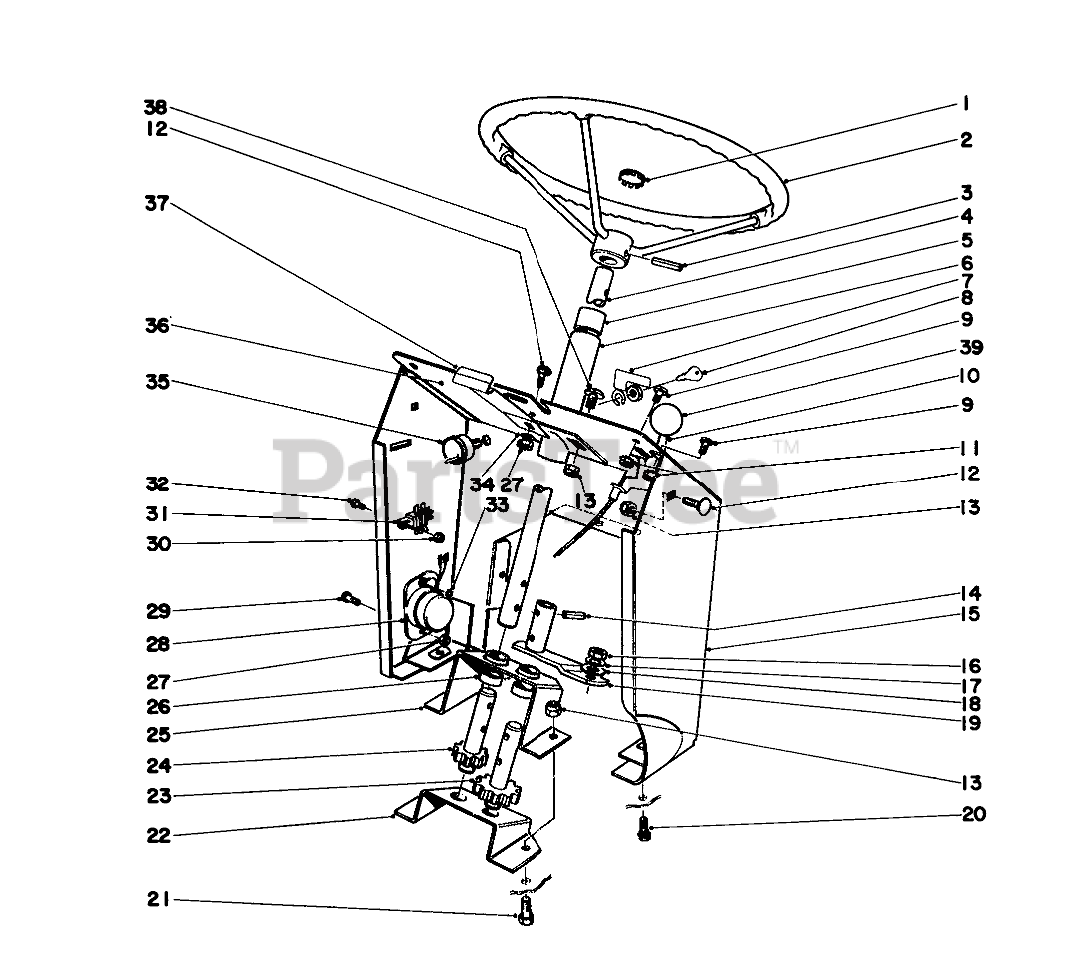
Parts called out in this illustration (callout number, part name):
2	Steering Wheel
3	PIN-ROLL
4	Shaft Steering
5	BUSHING
6	Steering Tube (Incl . Ref. #5)
7	Decal (Model 57003)
9	SCREW-PPH
10	Throttle Control
11	NUT-KEPS
12	SCREW-CARRIAGE
13	NUT-LOCK, CONE
14	PIN-ROLL, SLOTTED
15	Rear Hood Support (Model 57003)
16	NUT-HEX
17	WASHER-LOCK
18	WASHER-FLAT
19	Steering Arm
20	1/4-20X5/8 THDG SEMS
21	SCREW-HH
22	Bracket Steering
23	Steering Gear
24	Pinion Gear
25	Support Steering
26	Spacer
27	NUT-LOCK, CONE
28	Ignition Interlock
30	NUT-LOCK, NI
31	Terminal Block
32	SCREW-HEAD, PAN
33	WASHER-LOCK/EXT
34	WASHER-FLAT
35	Switch
36	Decal-Dash (Model 57131)
37	Hood Latch
38	Round Head Screw
39	KNOB-CONTROL
